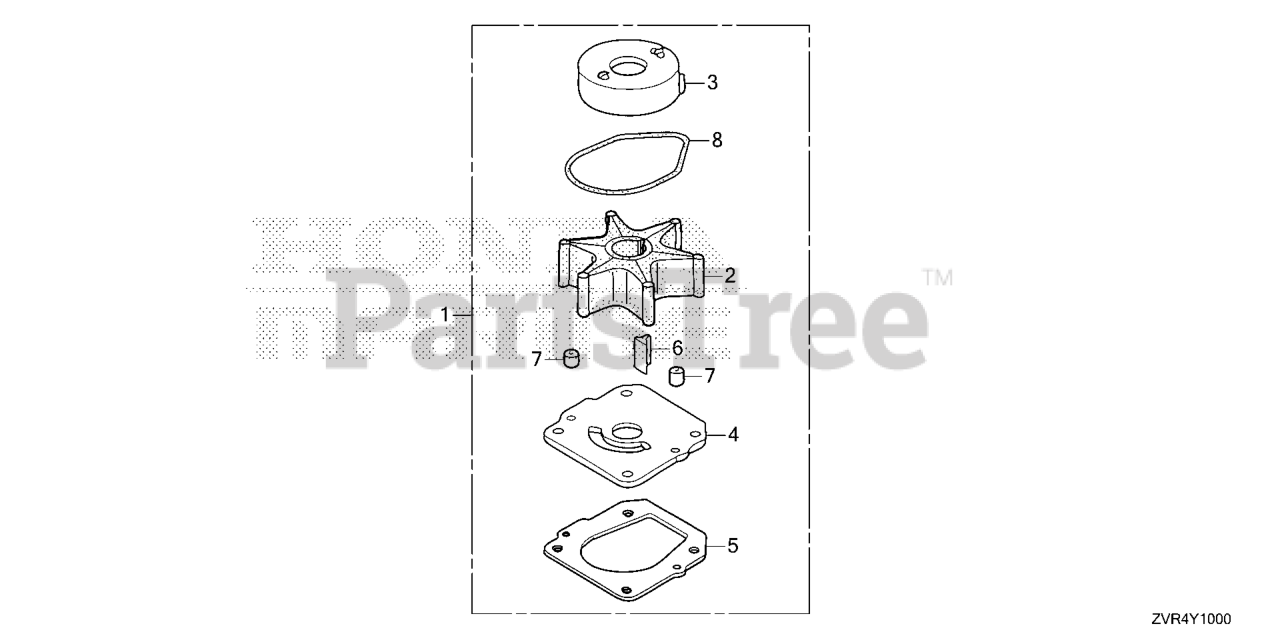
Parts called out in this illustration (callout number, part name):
1	PUMP KIT, IMPELLER
2	IMPELLER, PUMP
3	LINER, PUMP
4	COVER, IMPELLER
5	GASKET B, IMPELLER
6	KEY, WOODRUFF
7	PIN, DOWEL (6X10)
8	O-RING, WATER PUMP
